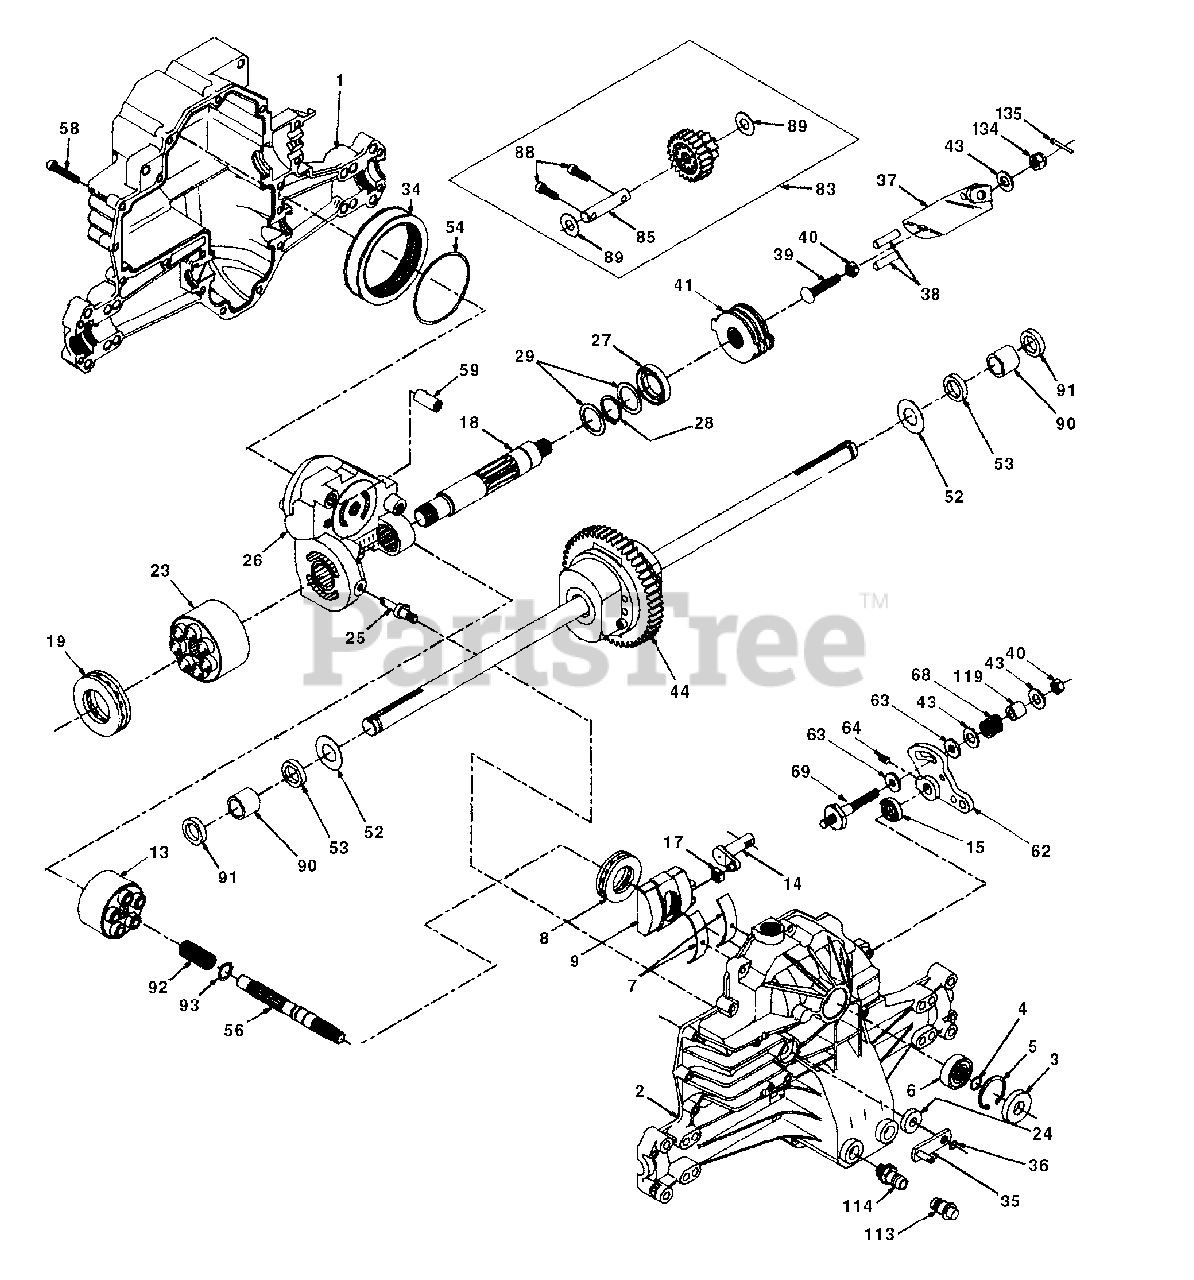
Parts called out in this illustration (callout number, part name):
1	Housing, Lower
2	Assembly, Upper Housing
4	Ring, Wire Retaining
5	Ring, Retaining
6	Bearing, Shaft Ball
7	Bearing, Cradle
8	Bearing, Thrust 30 x 52 x 13
9	Swashplate, Variable
13	Block, Cylinder Assembly
14	Arm, Trunnion
17	Guide, Slot
18	Shaft, Motor
19	Bearing, Thrust 42 x 68 x 16
23	Block, Cylinder Assembly
24	Seal, Lip 10 x 25 x 7
25	Actuator, Bypass
26	Center Section Assembly Kit
27	Seal, Lip 26 x 42 x 8
28	Ring, Retaining
29	Washer 26 x 35 x 1
34	Oil Filter Element
35	Arm, Bypass
36	Ring, Retaining
37	Arm, Actuating
38	Pin, Actuating
39	Bolt 5/16-24 x 1-3/4
40	Locknut, Hex 5/16-24 UNJC
41	Brake Rotor/Stator Kit
43	Washer 7/16 x 7/8 x .060
44	Differential Assembly
52	Washer 3/4 x 1.5 x .03
53	Seal .75 x 1.25 x .250
54	O-Ring .103 x 2.987 ID
56	Shaft, Input
58	Bolt 1/4-20 x 1.38
59	Pin .5 OD x .43 ID x .750
62	Arm, Control
63	Puck, Dampener
69	Stud 5/16-24
83	Jack Shaft Assembly
85	Jack Shaft
90	Sleeve Bearing
91	Seal, Wiper
92	Spring, Block
93	Washer, Block Thrust
113	Cap, Vent Assembly
114	Fitting, O-Ring Assembly
119	Spacer
134	Nut, Castle 5/16-24
135	Pin, Cotter
